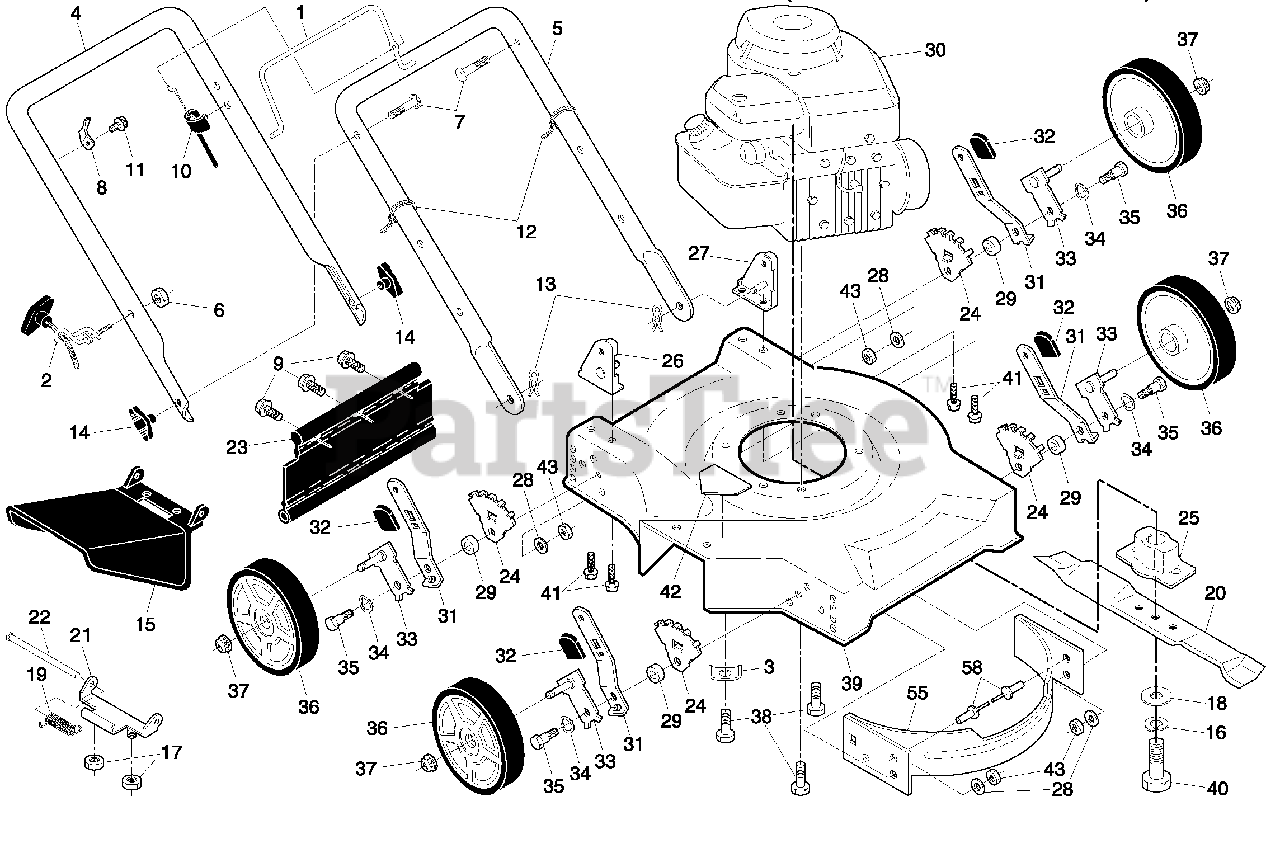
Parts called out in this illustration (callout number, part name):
1	Control Bar
2	Rope Guide
4	Upper Handle
5	Lower Handle
7	Handle Bolt 5/16-18 x 1-3/4
8	Up-Stop Bracket
9	Hex Washer Head Screw #10-24 x 1/2
10	Engine Zone Control Cable
11	Screw
12	Wire Tie
13	Hairpin Cotter
14	Knob, Handle
15	Discharge Guard
16	Helical Lock Washer 3/8
17	Locknut, Hex 1/4-20
18	Hardened Washer
19	Torsion Spring
20	Blade, 20"
21	Hinge Deflector
22	Hinge Rod
23	Rear Deflector
24	Wheel Adjusting Bracket
25	Blade Adapter
26	Handle Bracket Assembly, RH
27	Handle Bracket Assembly, LH
28	Washer, Flat
29	Spacer
31	Selector Spring
32	Selector Knob
33	Axle Arm Assembly
34	Belleville Washer
35	Shoulder Bolt
36	Wheel and Tire Assembly
37	Nut, Hex
38	Hex Head Thread Rolling Screw 3/8-16 x 1-1/8
39	Lawn Mower Housing
40	Hex Head Screw 3/8-24 x 1-3/8 Grade 8
41	Thread Cutting Screw 5/16-18 x 3/4
42	Danger Decal
43	Locknut, Hex 3/8-16
55	Baffl e, Front
58	Pop Rivet
58	Operator’s Manual, English
58	Operator's Manual, Spanish
58	Repair Parts Manual, English
